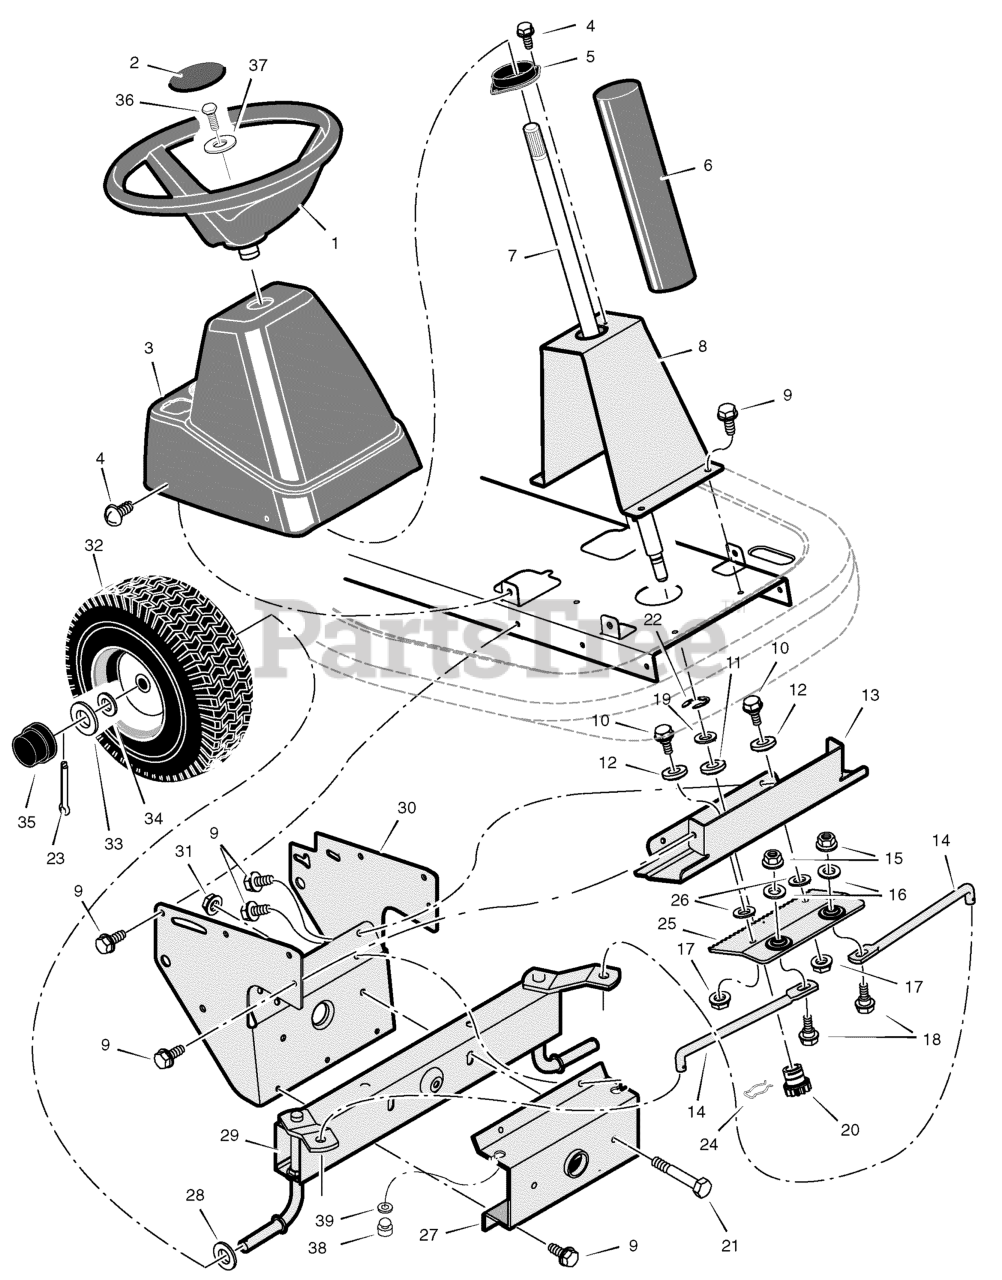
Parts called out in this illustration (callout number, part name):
1	Wheel, Steering
2	Insert, Steering Wheel
3	Console, Low -Black
4	Screw
5	Bearing, Upper Steering
6	Tube, Steering
7	Shaft, Steering
8	Support, Steering
9	Screw
10	Bolt, Shoulder
11	Bearing, Lower Steering
12	Roller
13	Plate, Gear Mounting
14	Link, Drag
15	Nut, Flange
16	Washer
17	Nut, Flange
18	Bolt, Hex
19	WASHER, 1-1.3 16G FLT
20	Gear, Pinion
21	Bolt, Hex
22	E-Ring, Retainer
23	Pin, Cotter
24	Retainer, Spring
25	Rack, Steering
26	Washer
27	Bracket, Axle Front
28	Washer
29	Axle & Spindle Assembly
30	Bracket, Support
31	Nut, Flange
32	Wheel, Front *
33	Washer
34	Washer
35	Cap, Hub
36	Screw, Hex
37	Washer
38	Bumper, Rubber
39	Washer
